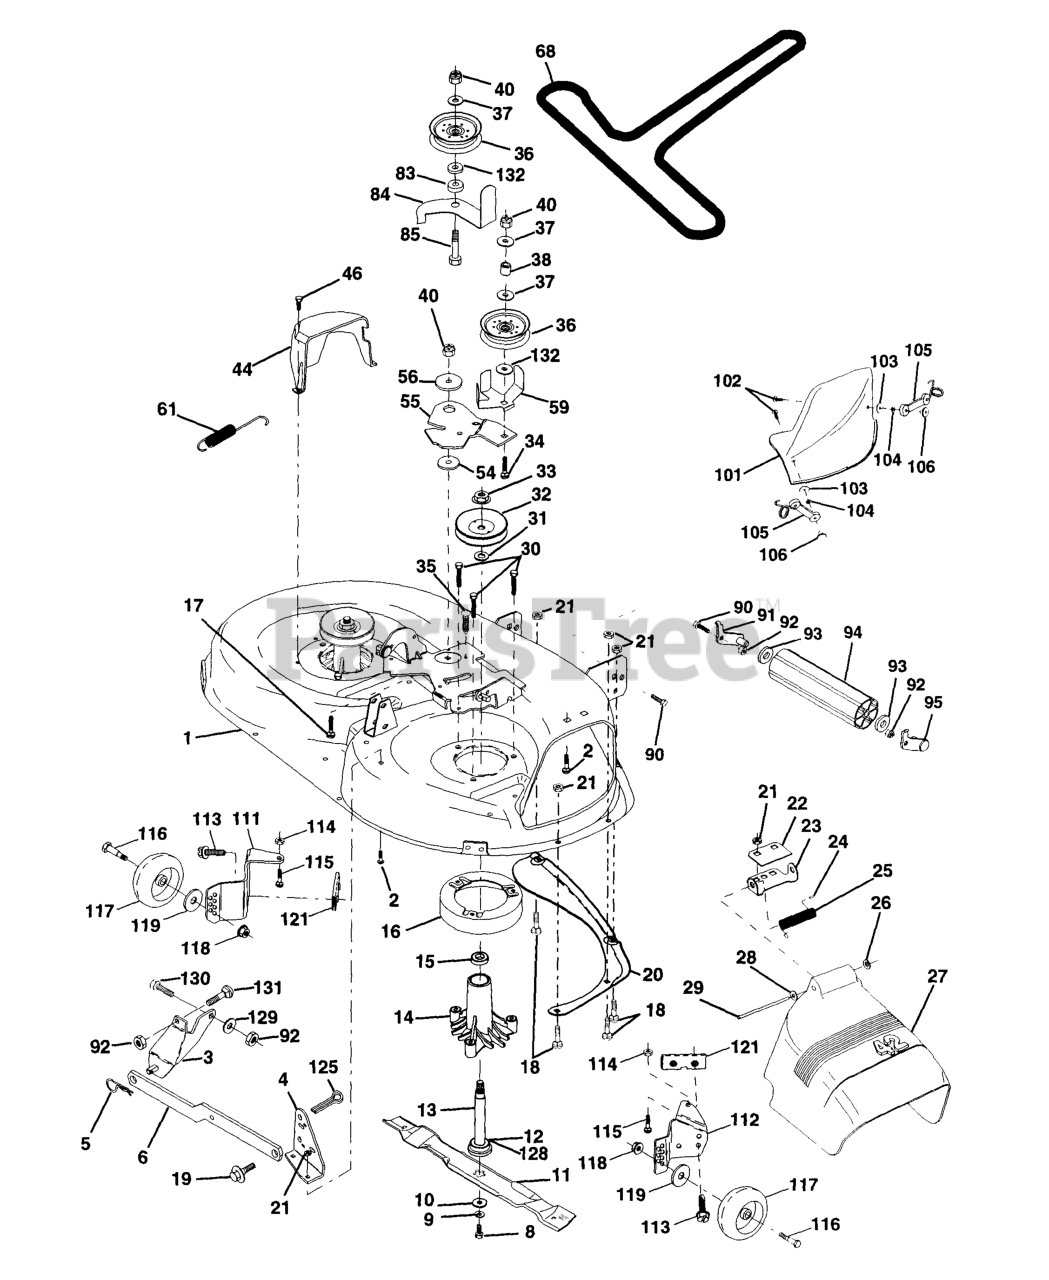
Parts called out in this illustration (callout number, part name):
1	DECK 42"
2	RP BOLT 5/16-18 X3/4 ZN/YEL GR
3	BRKT ASM SWAY BAR
4	BRKT DECK SW BAR
5	RETAINER-SPRNG RB
6	REAR SUSP ARM
8	BLADE BOLT
9	LOCKWASHER
10	WASHER.BLADE
11	BLADE.42".MULCH
12	BEARING.BALL.#6204.(MANDREL)
13	SHAFT ASM VENT
14	HOUSING.MANDREL.VENTED (MACHD)
16	STRIPPER
17	BOLT CARRIAGE
18	BOLT
19	BOLT SHD 5/16-18
20	BAFFLE
21	LOCKNUT
22	STIFFENER BRACKET
23	DEFLECTOR BRACKET
24	CAP-SLEEVE LT
25	SPRING TORSION
26	NUT PUSH M
27	SHIELD.DEFLECTOR.MOWER.42".BLK
28	Washer 11/32 X 5/8 X 16 Ga
29	ROD.HINGE
30	SCREW
31	WASHER
32	PULLEY/MANDREL
33	NUT
35	FASTENER.XMAS.TREE
36	FLAT IDLER PULLEY
37	WASHER
38	IDLER SPRING SPACER
44	GUARD MANDREL LH BLACK
46	SCREW.1/4-20X5/8
54	HARDENED WASHER
55	IDLER ARM
56	SPACER RETAINER
59	GUARD, BELT
61	SPRING EXTENSION
68	V-BELT TRIPATH
84	KEEPER.BELT.IDLER
85	BOLT
90	BOLT
91	BRACKET LH (A)
92	NUT
93	Washer 1 17/32 X 7/8 X 16 Ga
94	NOSE ROLLER
95	BRACKET RH (B)
101	COVER MULCH 42"
102	SCREW
104	LOCKWASHER #10
105	LATCH ASSEMBLY
106	WELDNUT
111	BRACKET WHEEL GAUGE LH 42" DK
112	BRACKET WHEEL GAUGE RH 42" DK
113	SCREW.THDROL.5/16-18X3/4.TTY
114	NUT
115	BOLT.CARR.5/16-18X1/2
116	BOLT, SHOULDER
117	WHEEL GAGE DONUT
118	LOCKNUT
119	WASHER.5/16.FLAT.STE.STD.
121	BRACKET.EXTRUDED.GAGE.WHEEL
125	Cotter Pin
128	WASHER FELT
129	WASHER
130	BOLT
131	BOLT D
132	Washer 13/32 x 1-3/8 x 3 Ga.
